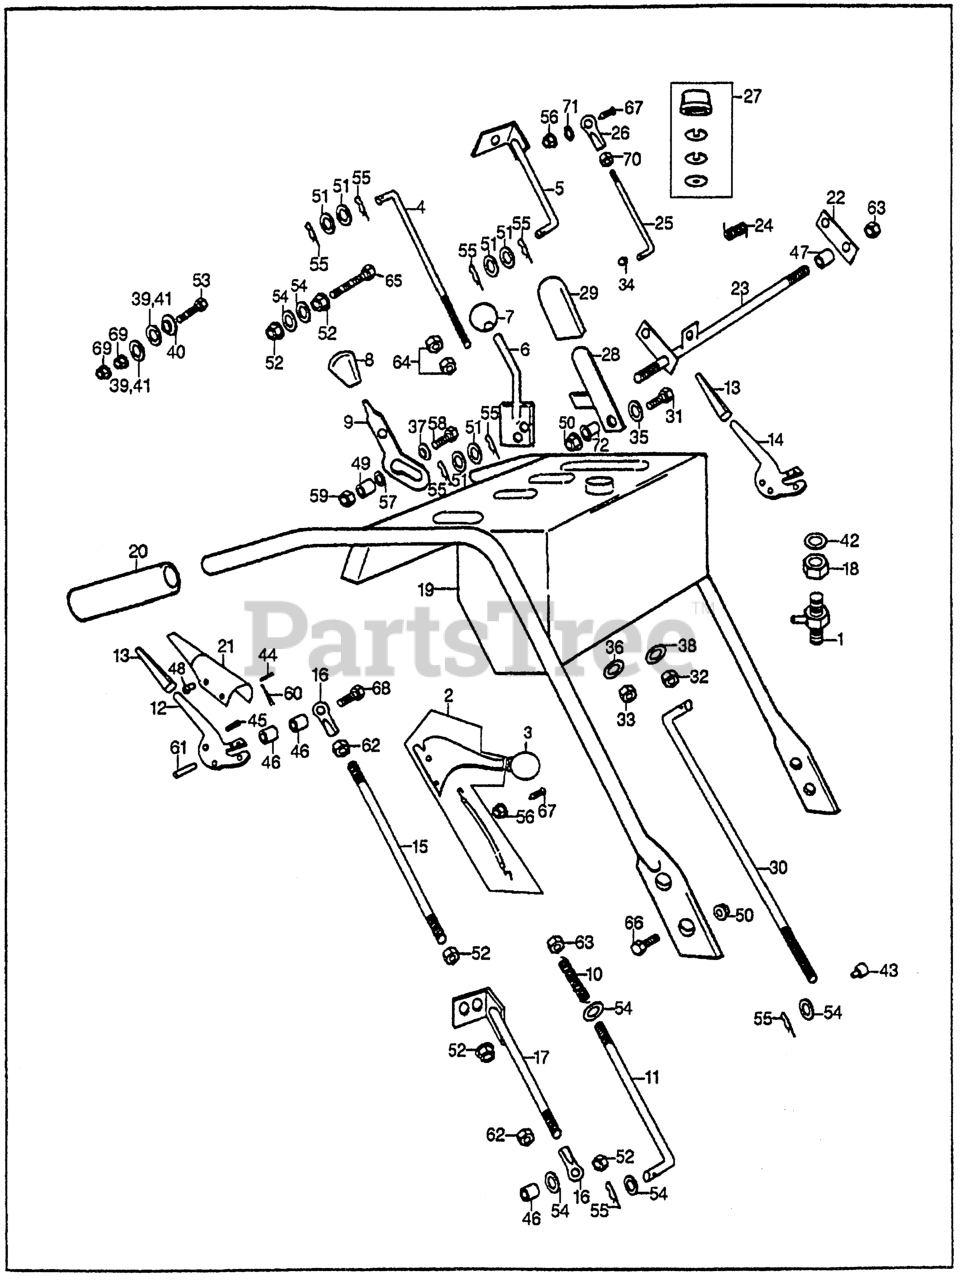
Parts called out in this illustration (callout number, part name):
1	VALVE, OIL SHUT-OFF (3/8")
2	CONTROL ASSY., THROTTLE
3	KNOB, THROTTLE
4	ROD A, GEARSHIFT
5	ROD B, CHANGE
6	LEVER, CHANGE
7	KNOB, CHANGE LEVER
8	KNOB, NEUTRAL LOCK
9	LEVER, NEUTRAL LOCK
10	SPRING, NEUTRAL Use up to Frame SN 1000677.
11	ROD, NEUTRAL
12	LEVER, R. TRACTION
13	GRIP, TRACTION LEVER
14	LEVER, L. TRACTION
15	ROD A, TRACTION
16	END, ROD (5/16")
17	ROD B, TRACTION
18	ADAPTER, OIL DRAIN
20	GRIP, HANDLE
21	LEVER, PRESENCE
22	ARM, LEVER PRESENCE
23	ROD, PRESENCE
24	SPRING, PRESENCE
27	CAP ASSY., RESERVOIR
28	LEVER, P.T.O. CLUTCH
29	GRIP, P.T.O. LEVER
30	ROD A, P.T.O.
31	BOLT A, SHOULDER
35	WASHER, BELLEVILLE (1/2") Use up to Frame SN 1000677.
36	WASHER A, SEAL
37	WASHER, BELLEVILLE
38	WASHER B, SEAL
39	WASHER, FRICTION THICK
40	WASHER, BELLEVILLE
41	WASHER, FRICTION THIN
42	WASHER, SEALING
43	PIN, PIVOT
44	PIN, PRESENCE LEVER
45	PIN, TRACTION LEVER
46	COLLAR, BEARING
47	COLLAR, PRESENCE
48	BUSHING, LEVER
49	COLLAR C, SPACER
72	BUSHING, SNAP
